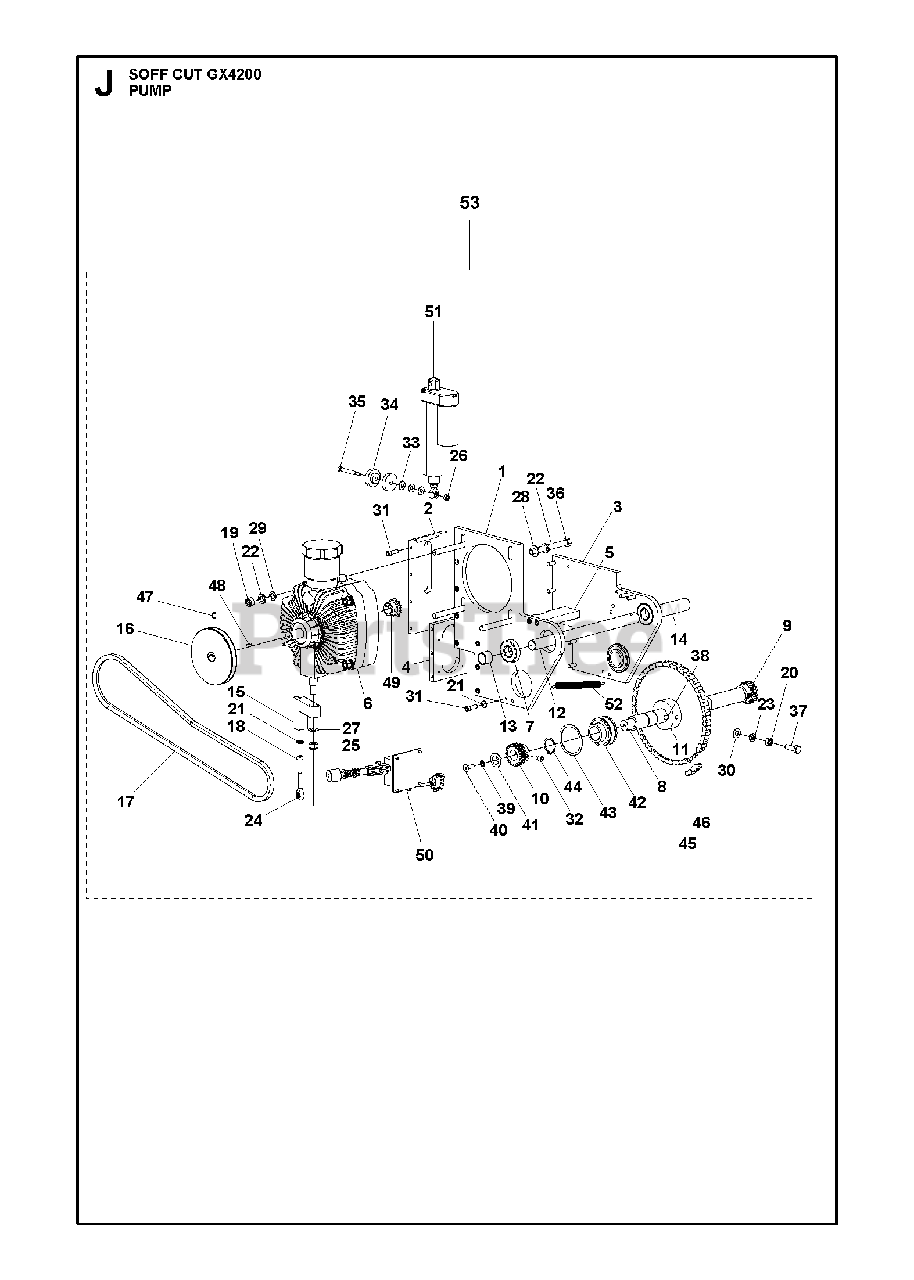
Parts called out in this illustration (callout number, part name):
1	PUMP SUPPORT PLATE RIGHT
3	PUMP SUPPORT PLATE LEFT
25	NUT
30	WASHER
47	SET SCREW 1/4-20-3/8 KNURLED P
